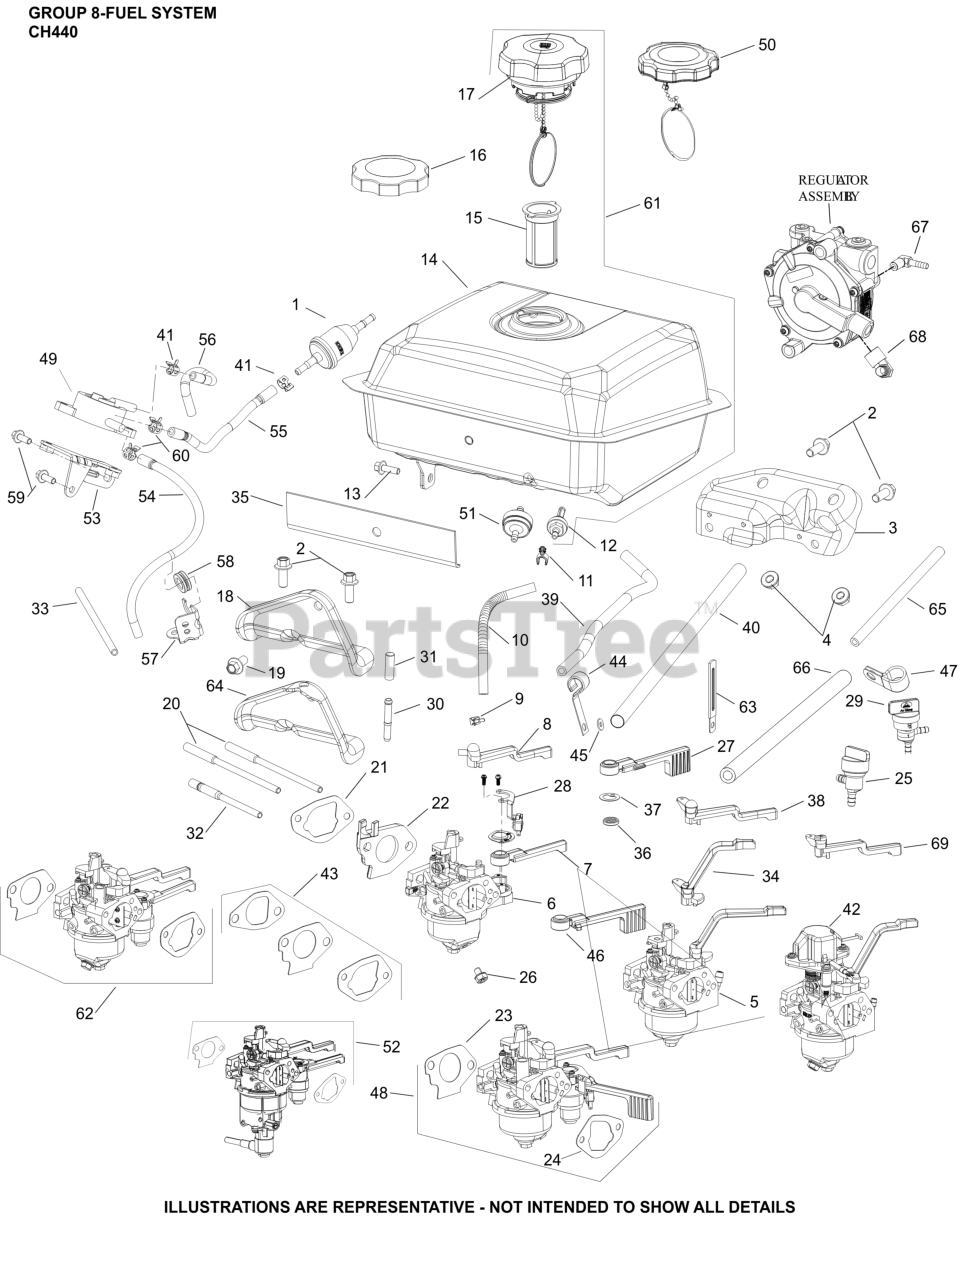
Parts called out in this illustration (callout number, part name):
2	SCREW, M8 X 20
3	BRACKET, FUEL SUPPORT ASSEMBLY
4	NUT, FLG M8X1.25
6	KIT, CARB COMPLETE
9	CLAMP, FUEL LINE
10	LINE, FUEL (10"-CUT TO LENGTH)
11	CLIP, FUEL HOSE
12	FITTING, FUEL ASSY
14	TANK, FUEL
15	FILTER, FUEL TANK
16	CAP, FUEL TANK
18	BRACKET, FUEL SUPPORT
19	SCREW, FLG 8X1.25X16
20	STUD, CARBURETOR
21	KIT, GASKET INTAKE
22	KIT, INSULATOR
23	GASKET, CARB TO INSULATOR
36	SEAL, INLET VALVE
37	KIT, FUEL SCREEN
NI	KIT, HIGH ALT (4000-8000 FT)
NI	KIT, HIGH ALT (8,000+ FT)
NI	KIT, CARBURETOR REPAIR
